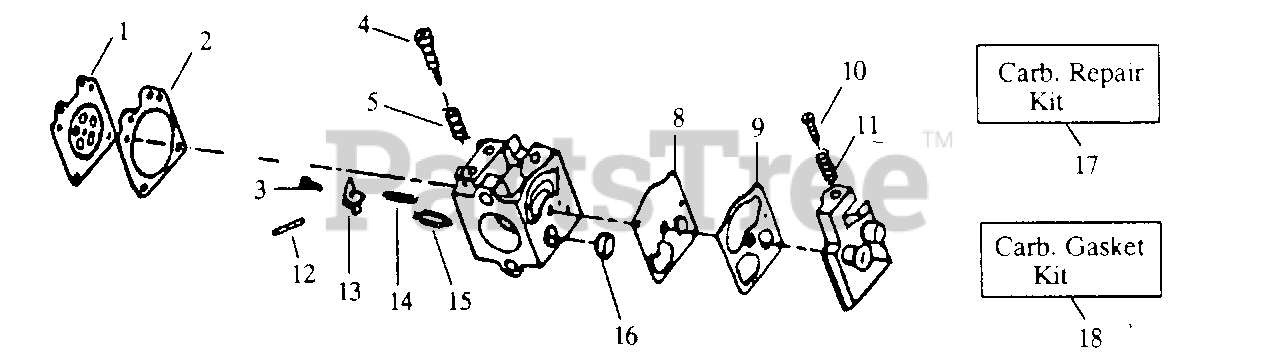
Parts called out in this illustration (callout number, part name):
1	Metering Diaphragm
2	Metering Diaphragm Gasket
3	Metering Lever Pin Screw
4	Mixture Needle
5	Mixture Needle Spring
8	Fuel Pump Diaphragm
9	Fuel Pump Gasket
10	Idle Speed Screw
11	Idle Speed Spring
12	Metering Lever Pin
13	Metering Lever
14	Metering Lever Spring
15	Inlet Needle Valve
16	Fuel Inlet Screen
17	Carb. Kwik Repair Kit
18	Carb. Gasket/Diaphragm Kit
